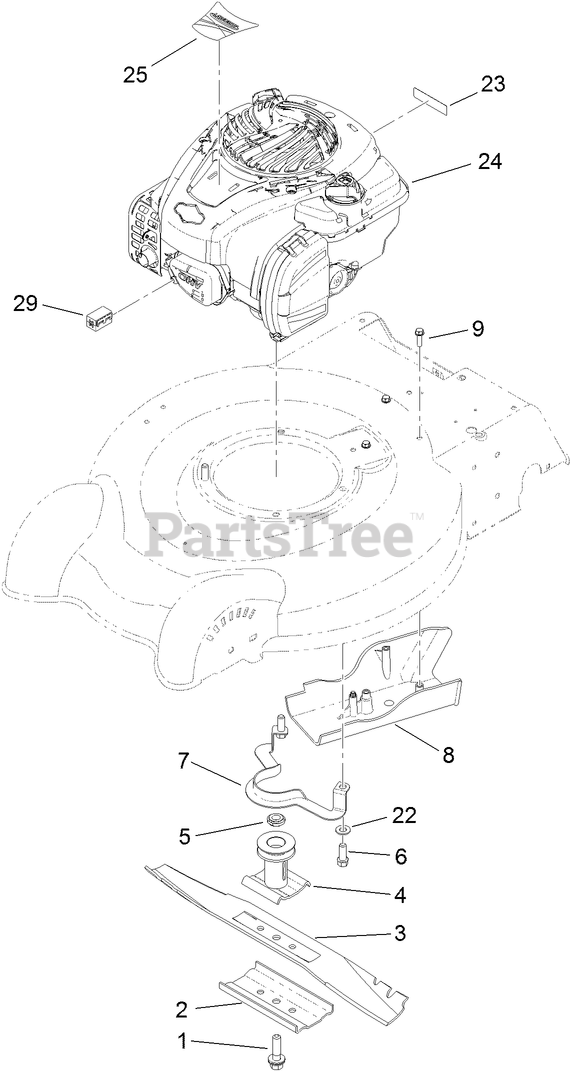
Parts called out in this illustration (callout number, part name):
1	BOLT-BLADE
2	SUPPORT-BLADE
4	DRIVER-BLADE
5	SPACER-DRIVER
6	SCREW-TAPTITE
8	COVER-BELT
9	SCREW-HWH
22	WASHER-FLAT
23	DECAL-ARRESTER, SPARK
25	DECAL-ENGINE
29	FERRITE-CLAMP
